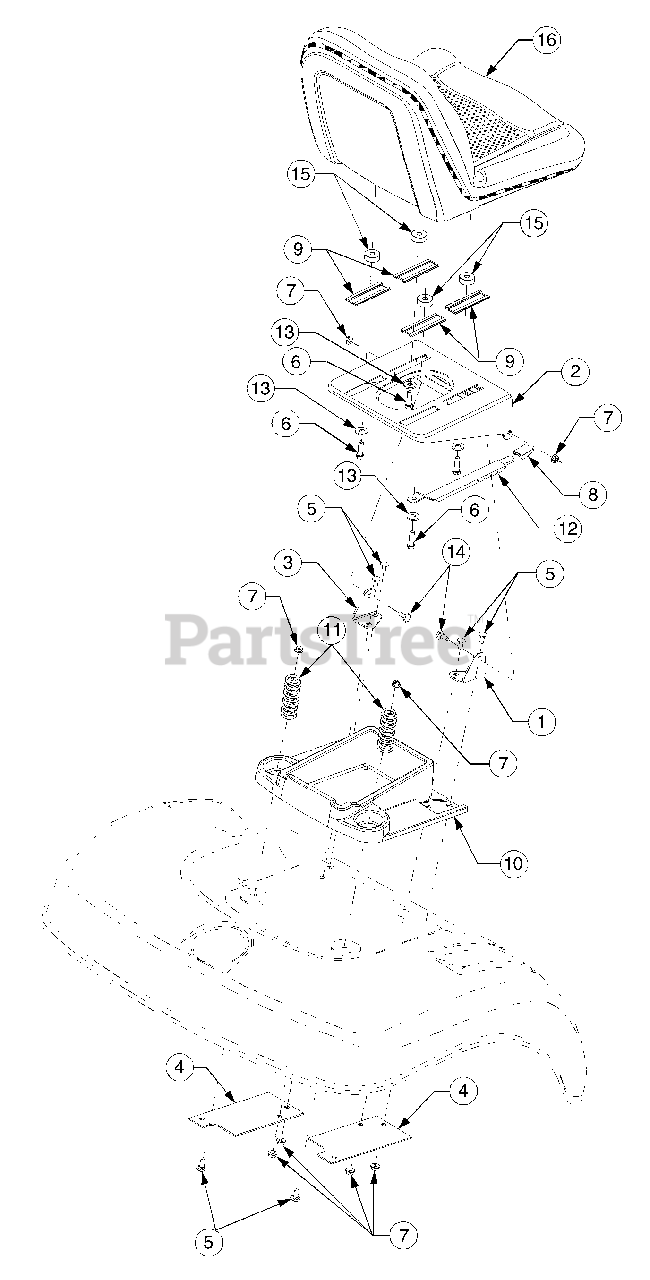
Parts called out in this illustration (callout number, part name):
6	Screw, Hx Cap Lock, 3/8-16 x 1.5 GR5
7	Nut, Hex Flange Lock, 5/16-18
8	Knob, Seat Adjuster
9	Slide, Seat
10	Tray, Tool
11	Spring, Comp, 1.28 OD x 4.5
12	Index Spring, Seat Adjuster
13	Washer, Flat, .406 x 1.0 x .105
14	Bolt, Shoulder
15	Spacer, Seat Slide Shoulder
16	Seat, High Back
